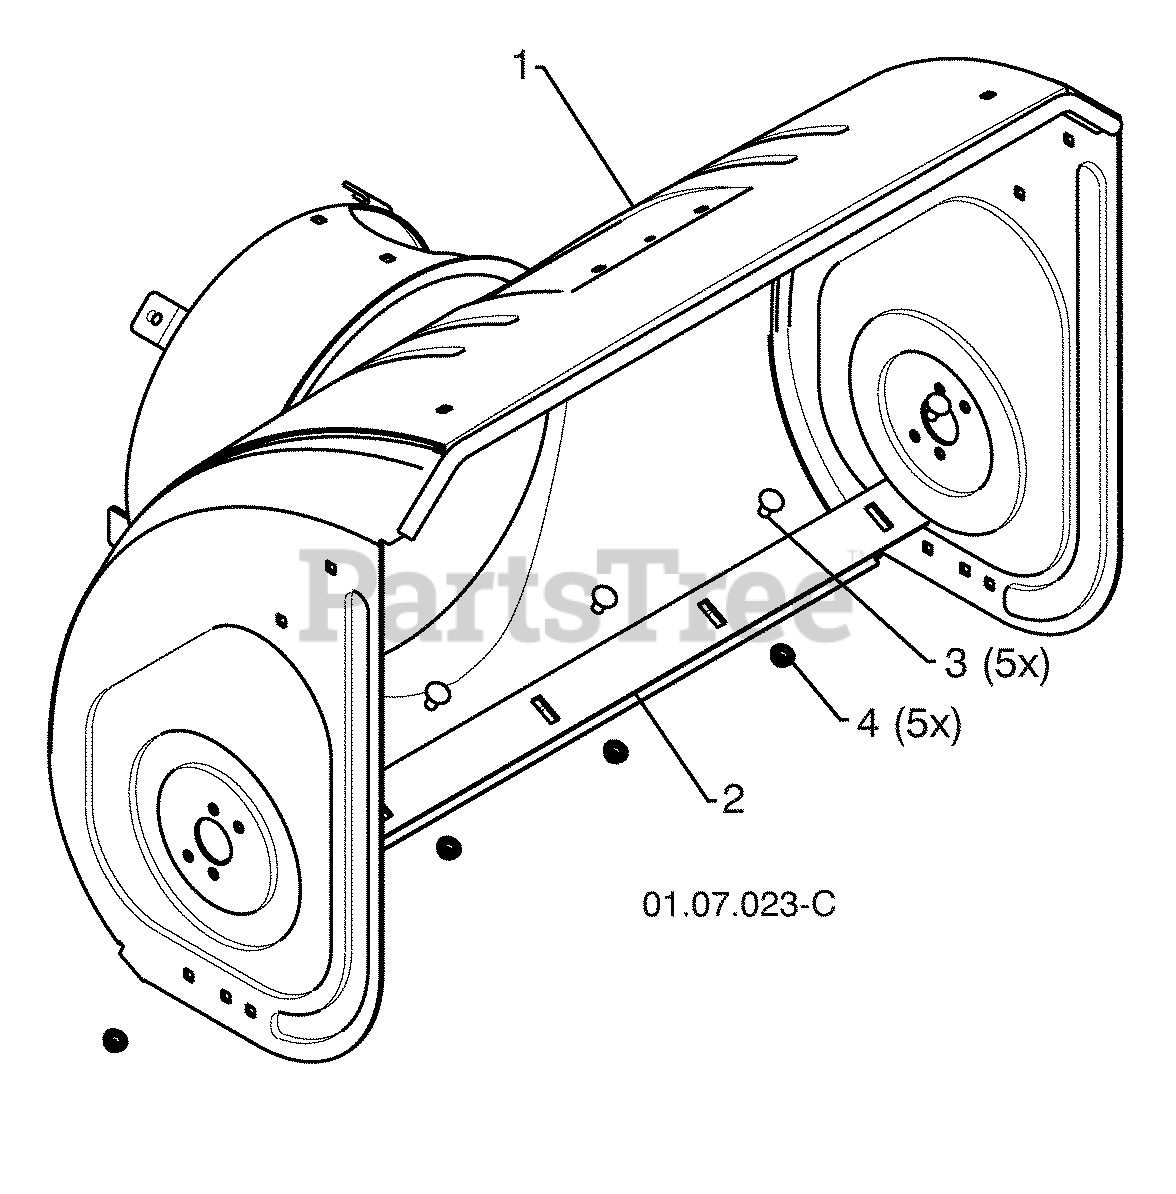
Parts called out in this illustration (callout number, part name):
1	AUGER HOUSING
2	SCRAPER BAR
3	CARRIAGE BOLT 5/16-18 X .625
4	NUT 5/16-18
